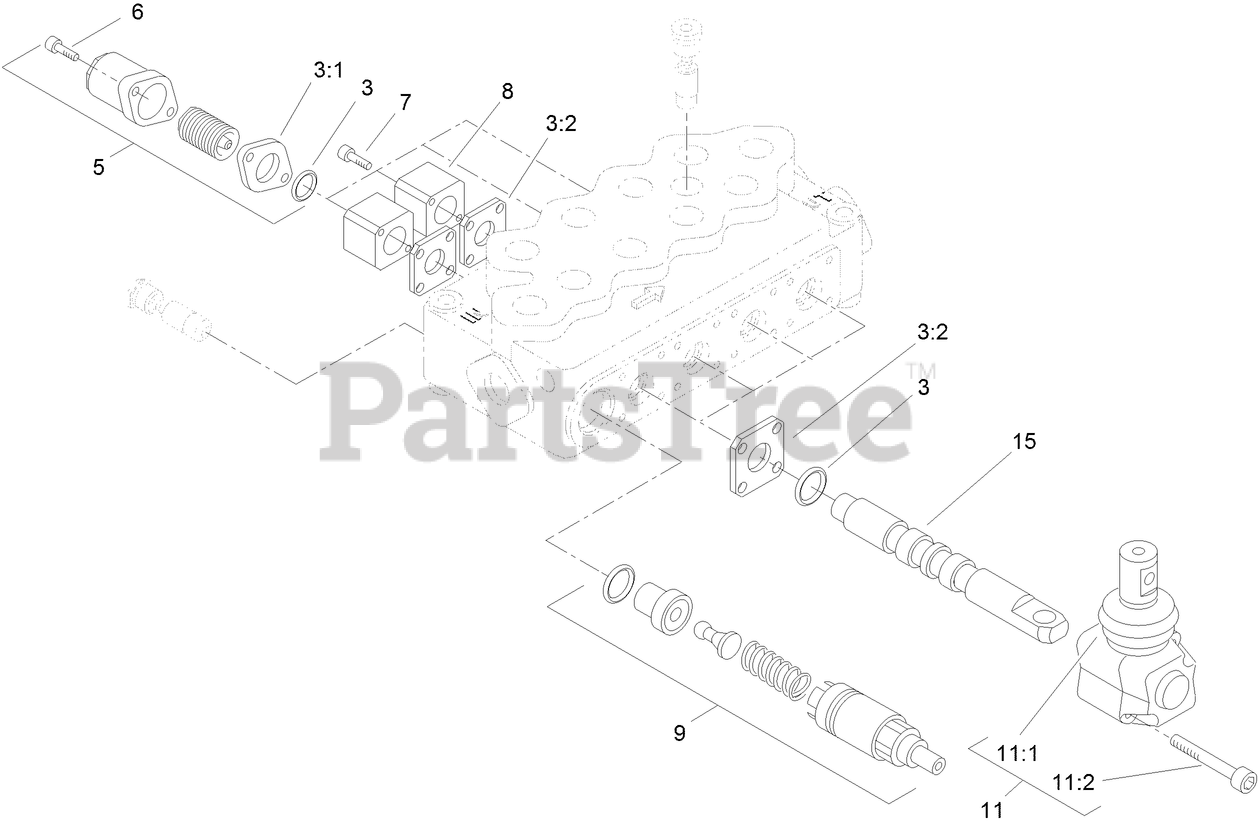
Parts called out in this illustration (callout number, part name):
3	SEAL KIT
3:1	GASKET
3:2	GASKET
5	STANDARD SPRING KIT
5	HIGH FORCE SPRING KIT
6	SCREW-CAP, END
8	BLOCK-MOUNT, SWITCH
9	VALVE-RELIEF
11	OPERATOR ASM
15	SPOOL-VALVE
